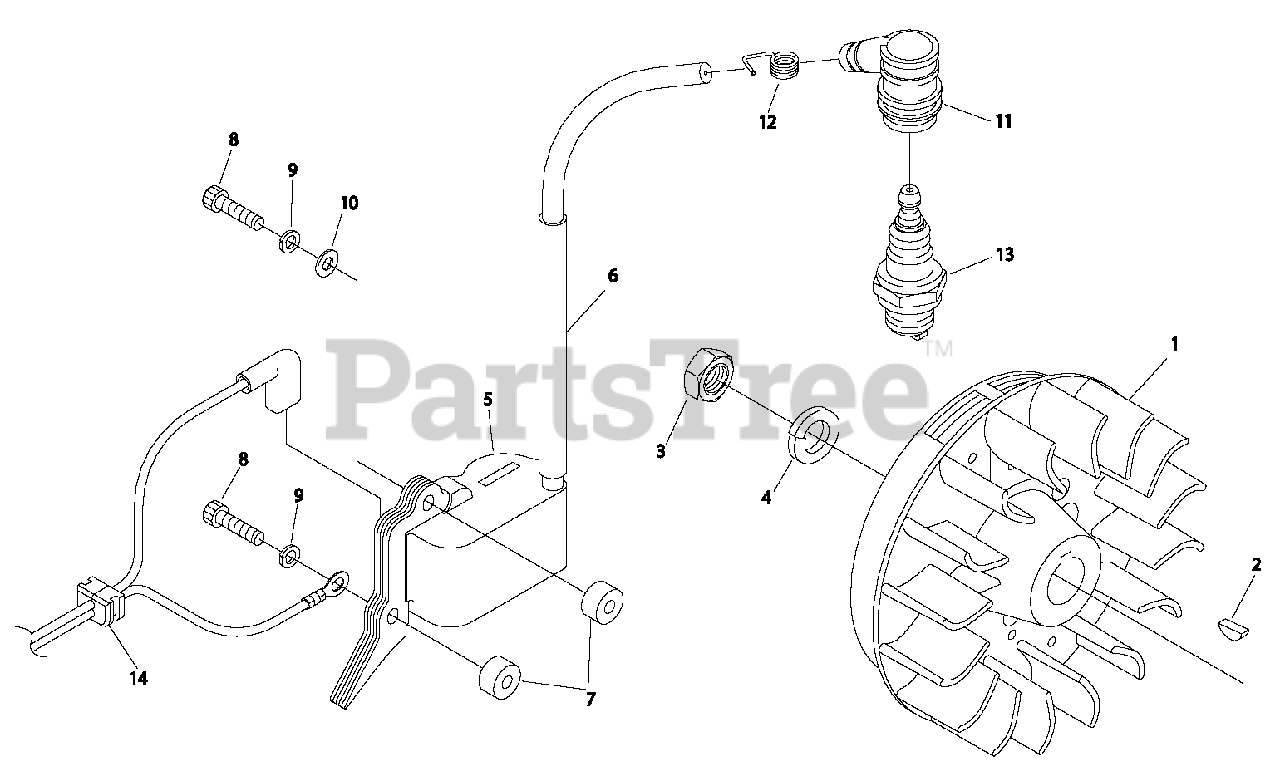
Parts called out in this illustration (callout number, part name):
1	FLYWHEEL
2	KEY - 3X10
3	NUT - 10
4	LOCKWASHER - 10
5	IGNITION COIL ASSY
6	TUBE, INSULATOR
7	INSULATOR
8	BOLT - 4X24
9	LOCKWASHER - 4
10	WASHER
11	CAP, SPARK PLUG
12	TERMINAL, SPARK PLUG CAP
13	SPARK PLUG -- BMR-6A
14	GROMMET
